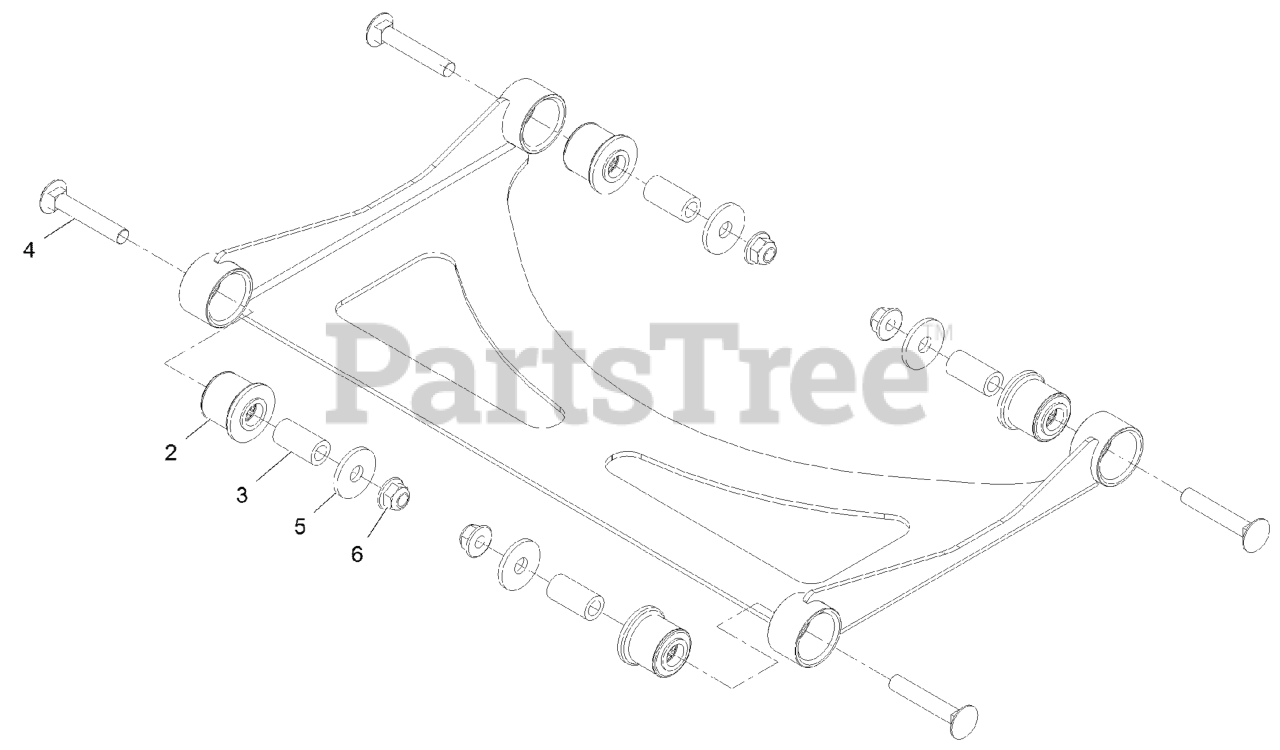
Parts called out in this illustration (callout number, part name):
2	BUSHING-RUBBER, SUSPENSION
4	Bolt-Carriage 3/8-16 X 2 1/4
5	WASHER
6	NUT-HF, NI
